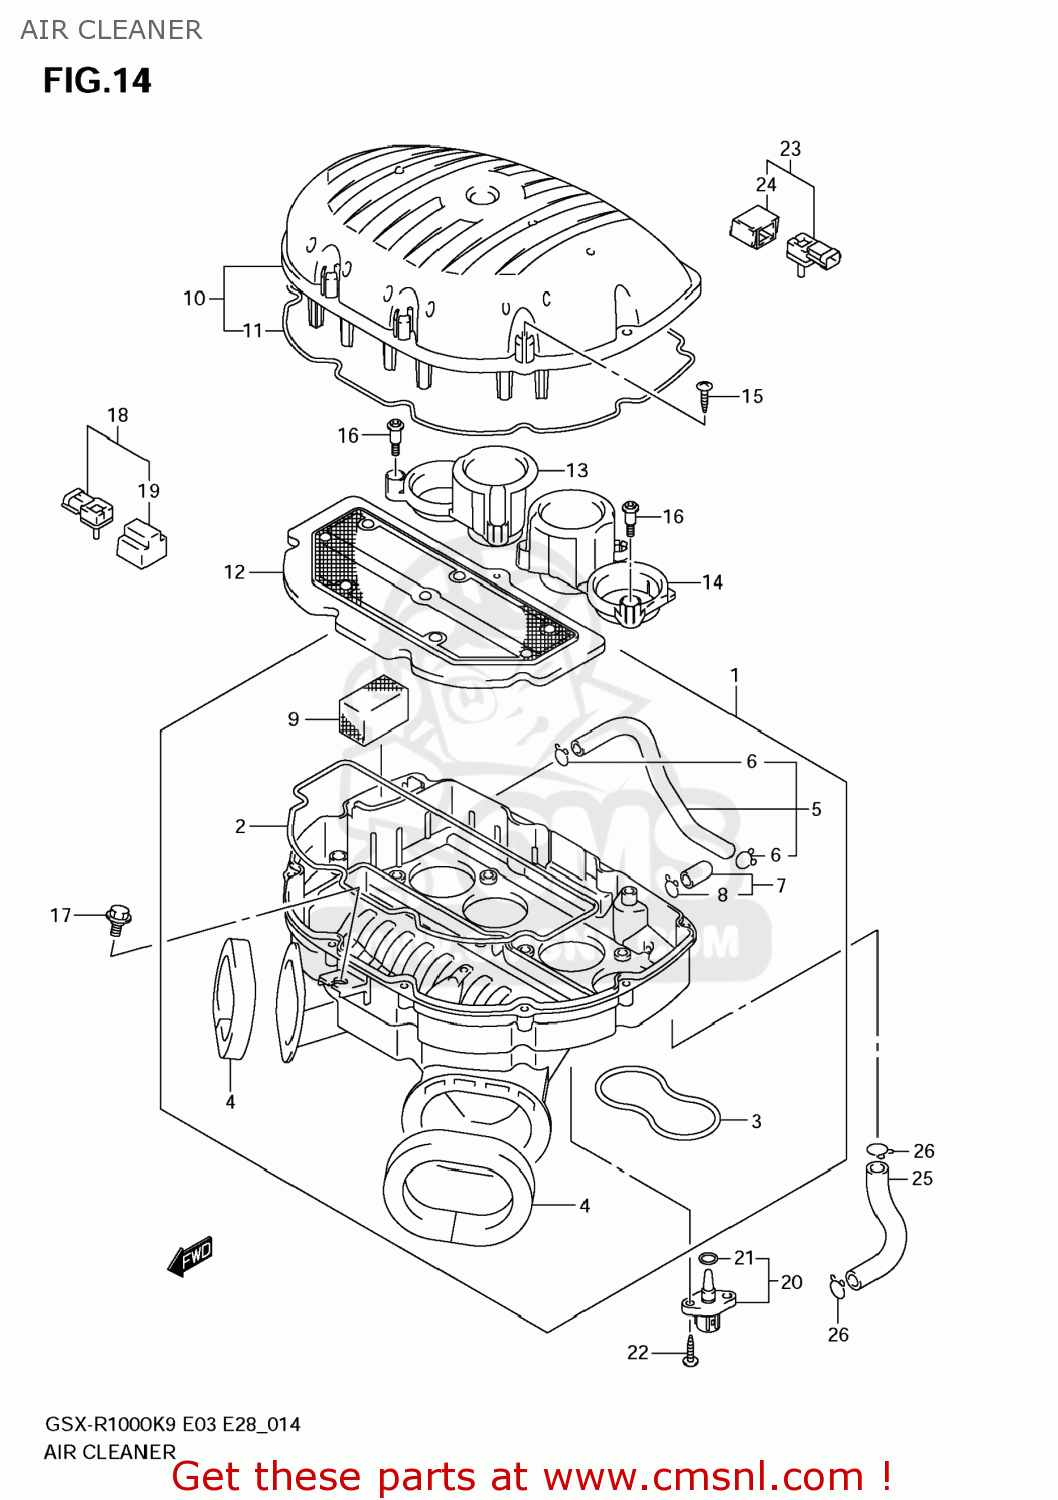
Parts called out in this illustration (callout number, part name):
1	CASE,AIR CLEAN
2	GASKET,CASE (NAS)
3	GASKET,CASE (NAS)
4	CUSHION,DUCT
5	TUBE,BREATHER
6	CLIP
7	PLUG ASSY,DRAIN
8	CLIP
9	FILTER,BREATHER
10	CAP,AIR CLEANER
11	GASKET,CAP (NAS)
12	FILTER ASSY
13	FUNNEL,OUTLET,R
14	FUNNEL,OUTLET,L
15	SCREW
16	BOLT,AIR CLEANER CASE
17	BOLT(6X16)
18	SENSOR,BOOST
19	COVER
20	SENSOR,AIR TEM
21	O RING
22	SCREW
23	SENSOR,AIR PRESSURE
24	COVER
25	HOSE,ISC VALVE
26	CLIP
